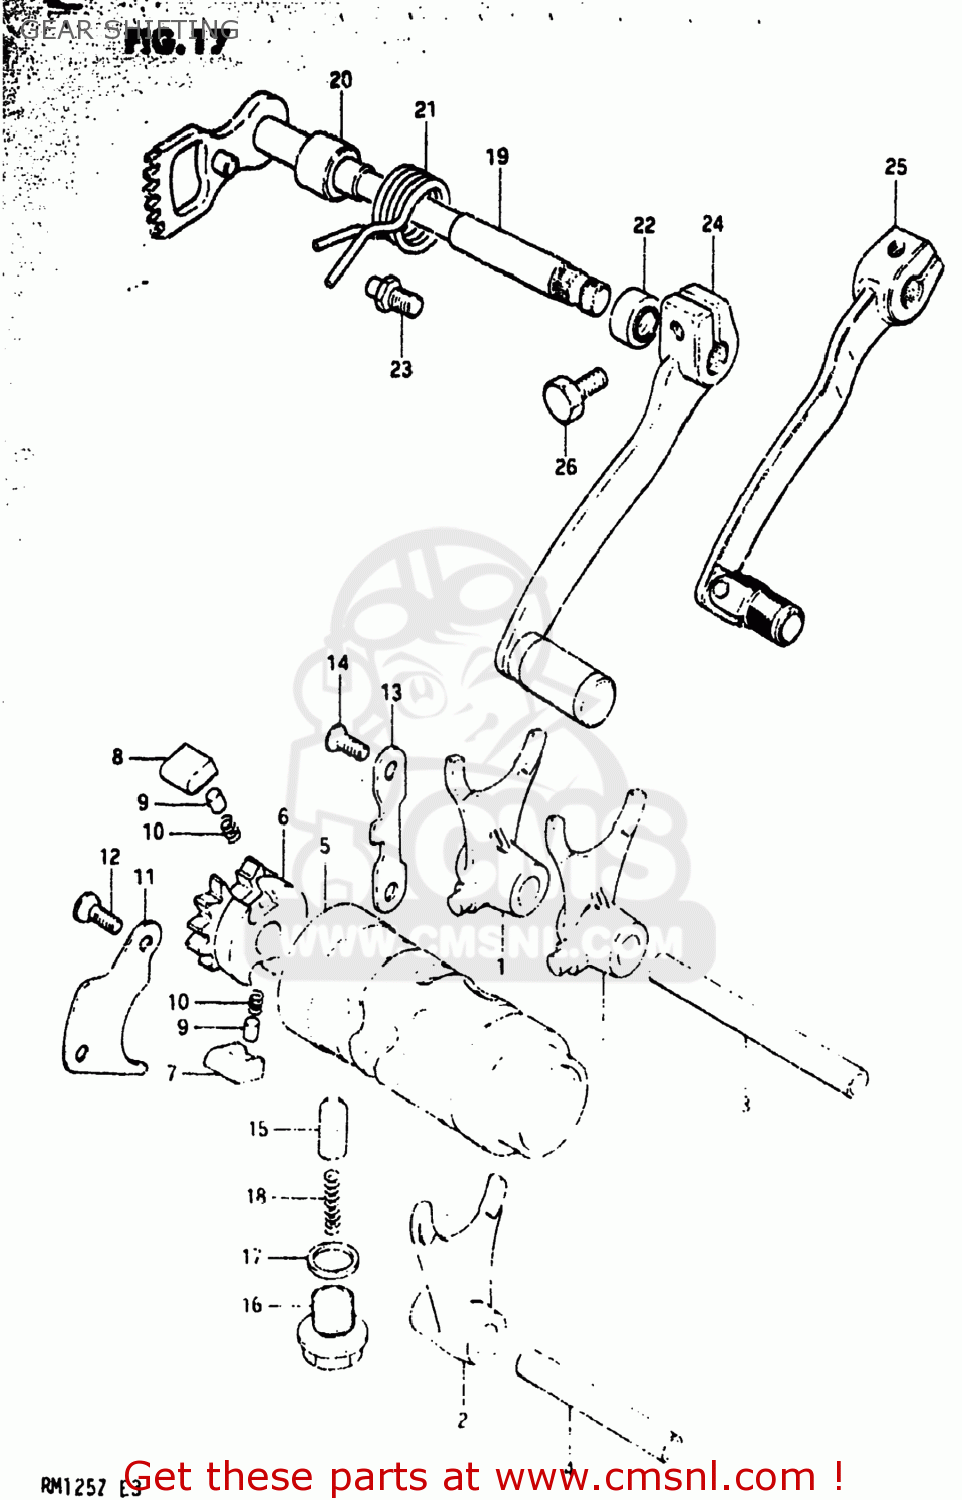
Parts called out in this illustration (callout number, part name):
1	FORK,GEAR SHIFT NO.1
2	FORK,GEAR SHIFT NO.2
3	SHAFT,GEAR SHIFT FORK
4	SHAFT,GEAR SHIFT FORK
5	CAM,GEAR SHIFT
6	RETAINER,GEAR SHIFT CAM
7	PAWL,GEAR SHIFT NO.1
8	PAWL,GEAR SHIFT NO.2
9	PIN(5X8)
10	SPRING
11	LIFTER,GEAR SHIFT PAWL
12	SCREW
13	GUIDE,GEAR SHIFT CAM
14	SCREW
15	STOPPER,GEAR SHIFTING
16	BOLT,GEAR SHAFT CAM STOPPER
17	GASKET(14X19.2X2) (NAS)
18	SPRING
19	SHAFT,GEAR SHIFT
20	SPACER(12X20X15.3)
21	SPRING
22	OIL SEAL
23	STOPPER,GEAR SHIFT CAM
24	LEVER,GEAR SHIFT
25	LEVER,GEAR SHIFT
26	BOLT
